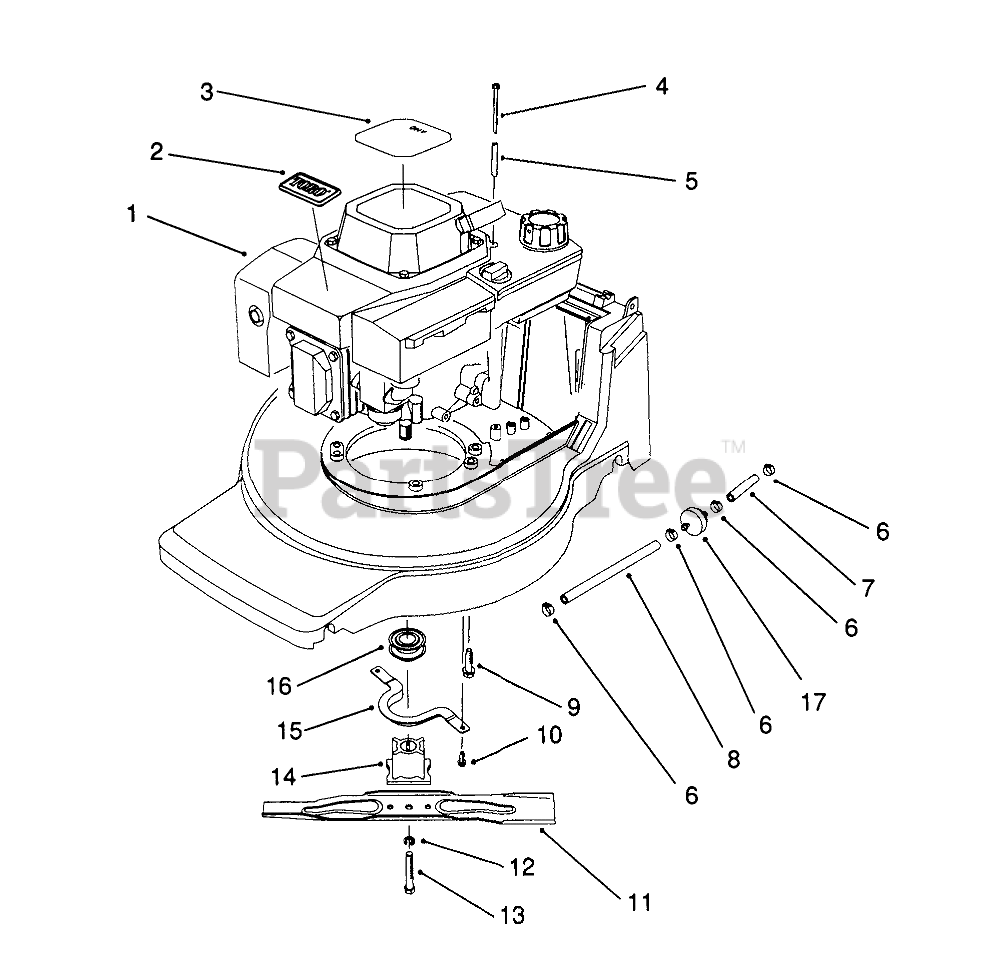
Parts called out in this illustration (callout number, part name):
1	Engine-OHV
2	TORO LOGO PLT
3	DECAL-HV INT'L
4	THRD FORMING SCREW
5	TUBULAR SPACER
6	CLAMP-FUEL LINE
7	LINE-GAS
8	HOSE-FUEL
9	SCREW-HWHTF
10	SCREW-HWH
11	Blade-48cm
12	WASHER-LOCK
13	BOLT-BLADE
14	BLADE RETAINER - 25 MM
15	Guide-Belt
16	PULLEY-DRIVE, ZONE START
17	FILTER-FUEL
